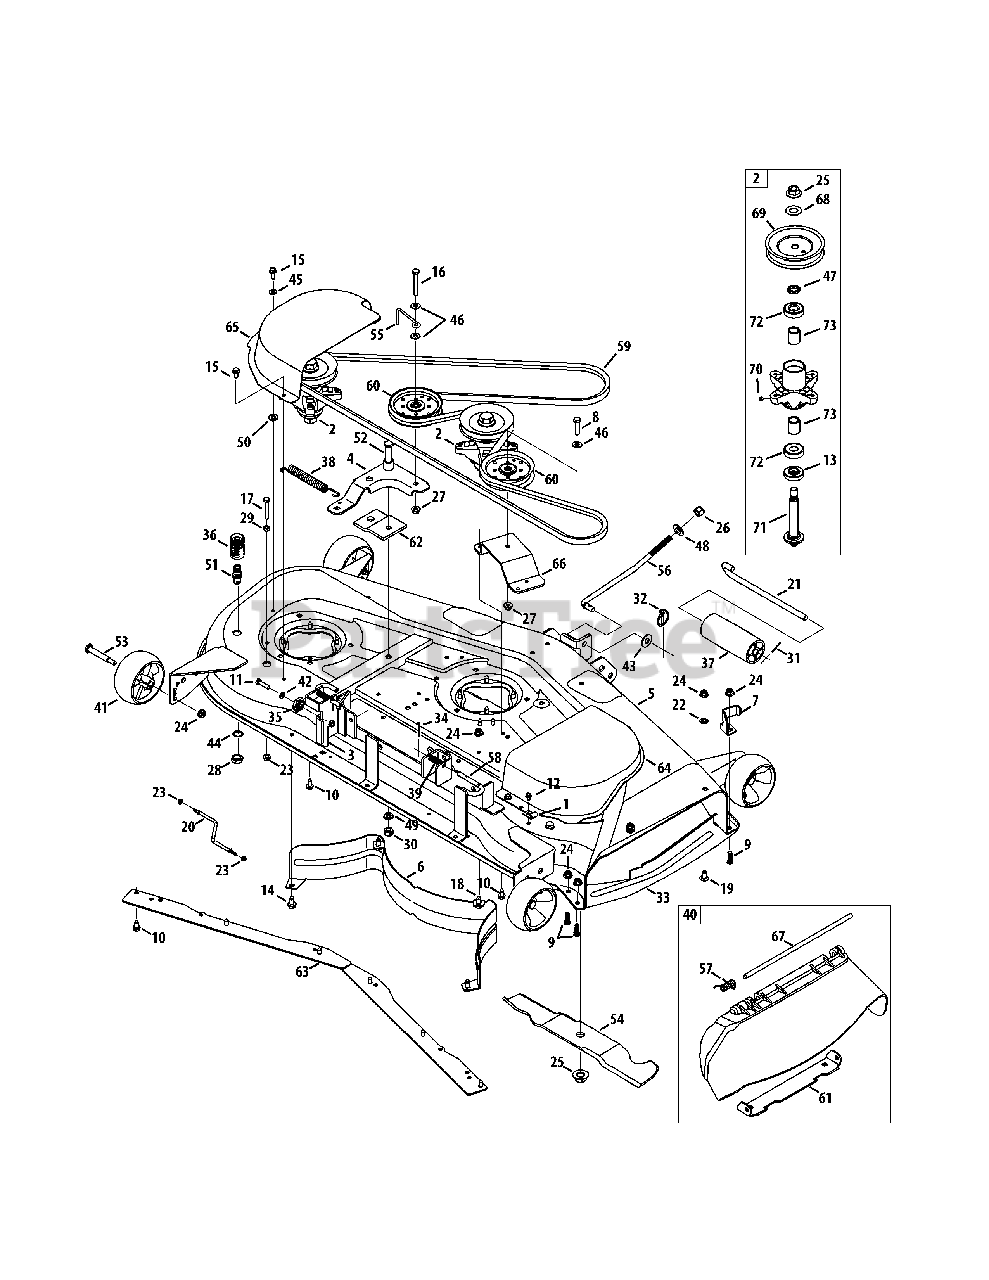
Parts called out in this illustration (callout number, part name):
1	Bracket, Hook, Retainer
2	Spindle Assembly, Pulley, 5.39 Dia.
3	Bracket Assembly, Deck, Hanger LH
4	Idler Assembly, Arm, 54"
5	Deck Assembly, 54"
6	Baffle, Rear
7	Stop, Chute, Deflector
8	Hex Screw, 3/8-16, 1.75, Gr5
9	Hex Screw, 3/8-16, 1.00, Gr5, Spec
10	Screw, Self-tapping, 5/16-18, .750,
11	Hex Screw, 5/16-18, 1.25, Gr5, Std
12	Screw, Self-tapping, 1/4-20, 0.500
13	Spacer, .79 x 1.82 x .55lg.
14	Screw, Self-tapping, 3/8-16, 0.750
15	Screw, Self-tapping, 5/16-18, 0.875
16	Hex Screw, 3/8-16, 2.50, Gr5, Std
17	Hex Screw, 5/16-18, 2.00, Gr5, Std
18	Bolt, Carriage, 3/8-16, 1.00, Gr5
19	Bolt, Carriage, 3/8-16, 0.75, Gr1
20	Rod, Support, Deck
21	Roller Pin-1/2 Dia. x 7.31
22	Nut, Push, 3/8
23	Nut, Flange Lock, 5/16-18, Nylon
24	Nut, Flange Lock, 3/8-16, Nylon
25	Nut, Flange, 5/8-18
26	Nut, 1/2-13
27	Nut, Flange Lock, 3/8-16, GrF
28	Nut, Hex, M16-1.5
29	Nut, Hex, 5/16-18, Gr5
30	Nut, Hex Lock, 1/2-13, GrB
31	Pin, Cotter, 3/32, 1.0
32	Pin, Lynch, .1875
33	Finger Guard
34	Pin, Cotter, 1/8 x 1.25
35	Gear, Deck, Adjustment
36	Coupler, Water
37	Roller, Front
38	Spring, Extension, .85 OD x 6.415
39	Spring, Compr’, .53 OD x 1.75
40	Chute Assembly
41	Wheel, Deck, 5.0 Dia. Ball
42	Washer, Lock, 5/16, Regular Duty
43	Washer, Flat, .531 x 1.25 x .100
44	Washer, Lock, 5/8, Int Tooth
45	Washer, Flat, .344 X .688 X .065
46	Washer, Flat, .406 x .875 x .059
47	Spacer, .790 x 1.25 x .175
48	Washer, Bell, .63 x 1.25 x .18
49	Washer, Lock, 1/2 , Regular Duty
50	Washer, Flat, .407x.812x.135
51	Port, Water
52	Bolt, Shoulder, .625 x 2.50, 1/2-13
53	Bolt, Shoulder, .496 x 2.50, 3/8-16
54	Blade, 18.50 Star 2 In 1
55	Rod, Keeper
56	Deck Lift Rod, Front, 11.7
57	Spring, Torsion, .44 I.D. x 2.0,
58	Rod, Deck Release
59	Belt, V-Type
60	Pulley, Idler, 4.25"Dia.
61	Bracket, Chute 50/54"
62	Bracket, Stabilizer, Pulley
63	Skirt, Deck, 54"
64	Cover, Belt, RH 54"
65	Cover, Belt, LH 54"
66	Bracket, Idler, Stationary
67	Pin, Hinge, .3175 Dia. x 14.06 ,1
68	Washer, Flat, .760 X 1.50 X .120
69	Pulley, Deck, 5.39 Dia.
70	Lube Fitting, 3/16
71	Shaft, Spindle, 5.75 Lg.
72	Bearing, Ball, .787id x 1.85 Od x .551
73	Spacer, .80 x 1.10 x 1.322
